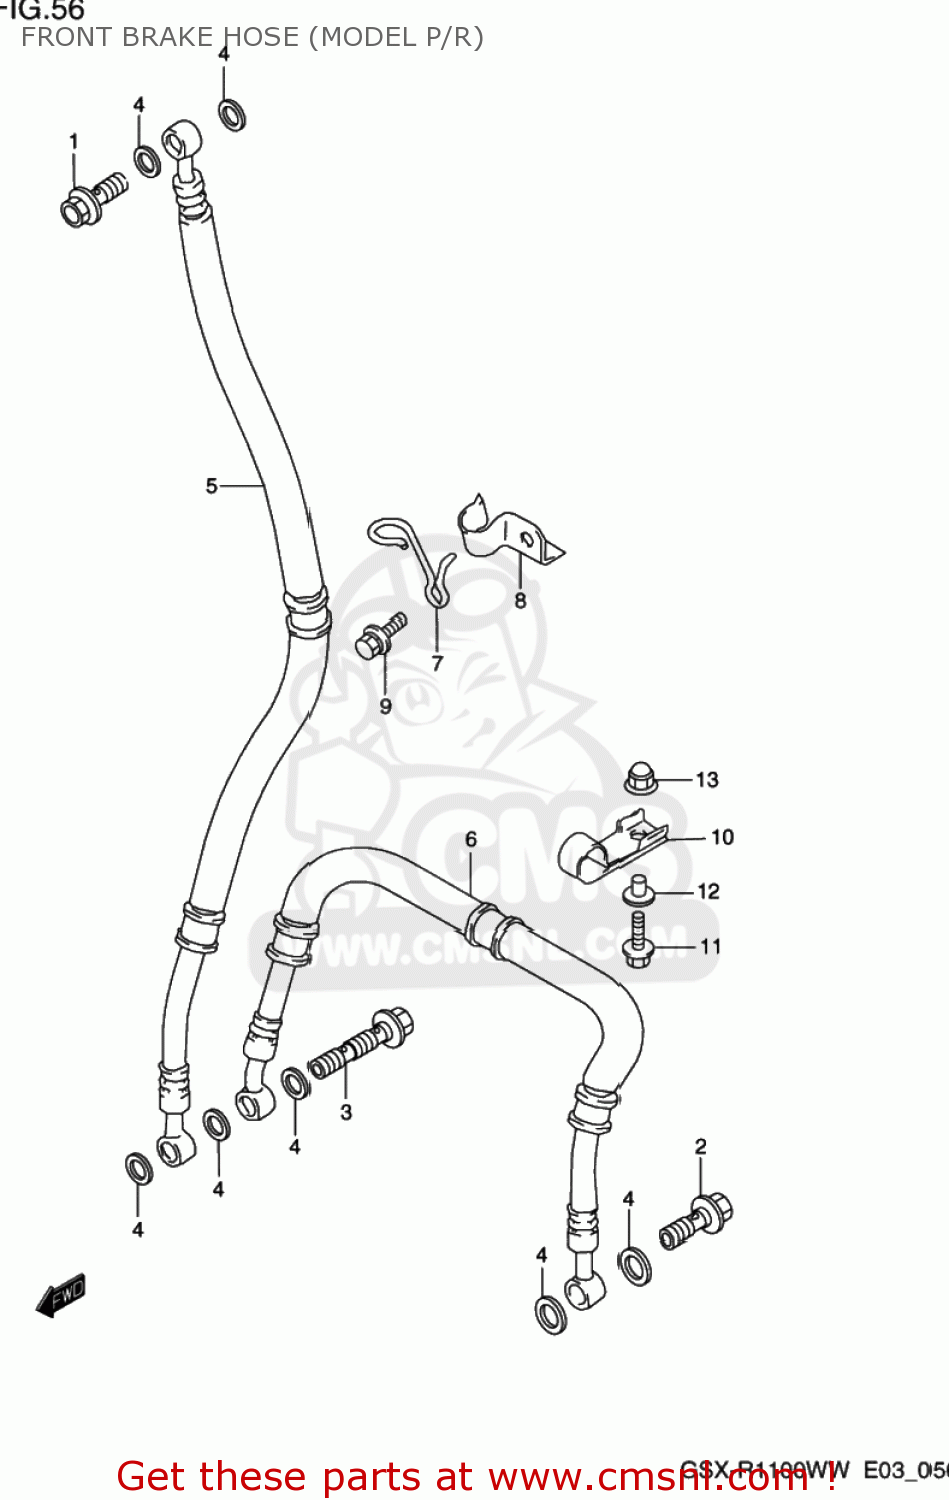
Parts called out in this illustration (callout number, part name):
1	BOLT UNION
2	BOLT UNION
3	BOLT UNION
4	WASHER(10X15X1.5)
5	HOSE COMP,FRONT BRAKE
6	HOSE COMP,FRONT BRAKE
7	CLAMP,FRONT BRAKE HOSE
8	CLAMP,FR BRAKE HOSE UPR
9	BOLT
10	CLAMP,FR BRAKE HOSE NO.2
11	BOLT
12	WASHER
13	NUT
